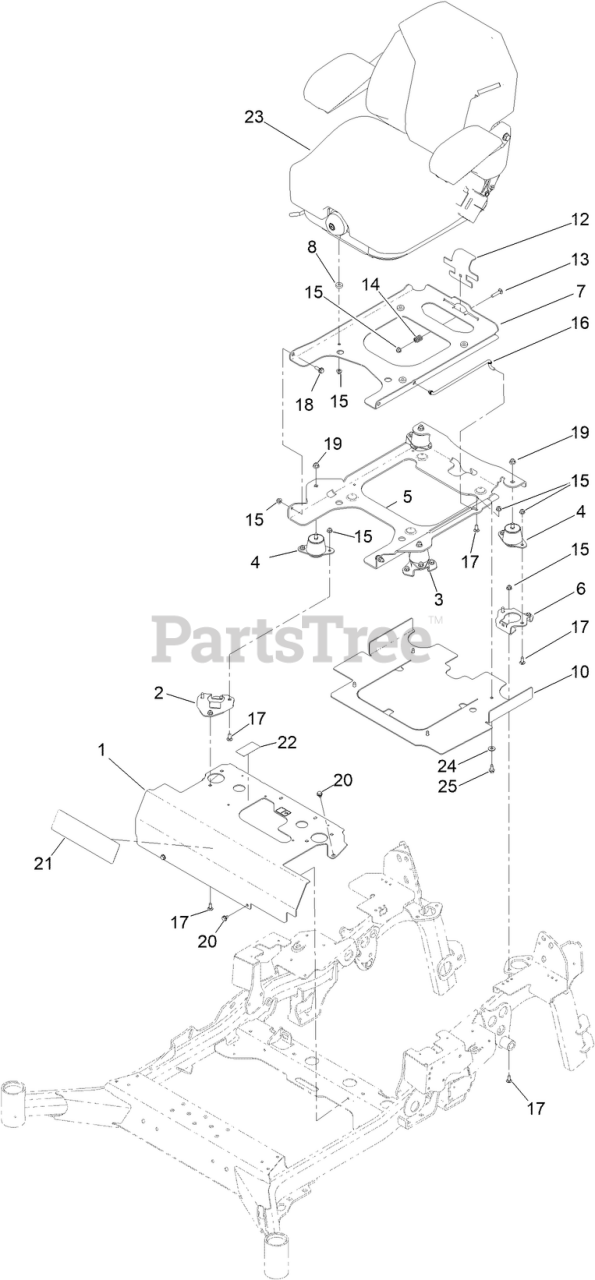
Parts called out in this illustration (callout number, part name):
1	MOUNT-SEAT W/DECALS
2	RISER-SEAT MOUNT, R
3	RISER-SEAT MOUNT, L
4	ISOLATOR-SEAT
5	PLATE,TILT SEAT SUPPORT
6	RISER-SEAT MOUNT, REAR
7	PLATE-FRAME, SEAT
10	SHIELD-HEAT
12	PLATE, SEAT LATCH
13	BOLT-CARR
14	SPRING-COMPRESSION
15	NUT-HF, NI
16	ROD-PROP
17	SCREW-CARR
18	SCREW-SHOULDER
19	NUT-HF, NI
20	SCREW
21	DECAL-CONSOLE
22	DECAL-FLUID, TRANSMISSION
23	ASM-SUSPENSION SEAT, TORO
24	WASHER-FLAT
25	SCREW-HWHTF
